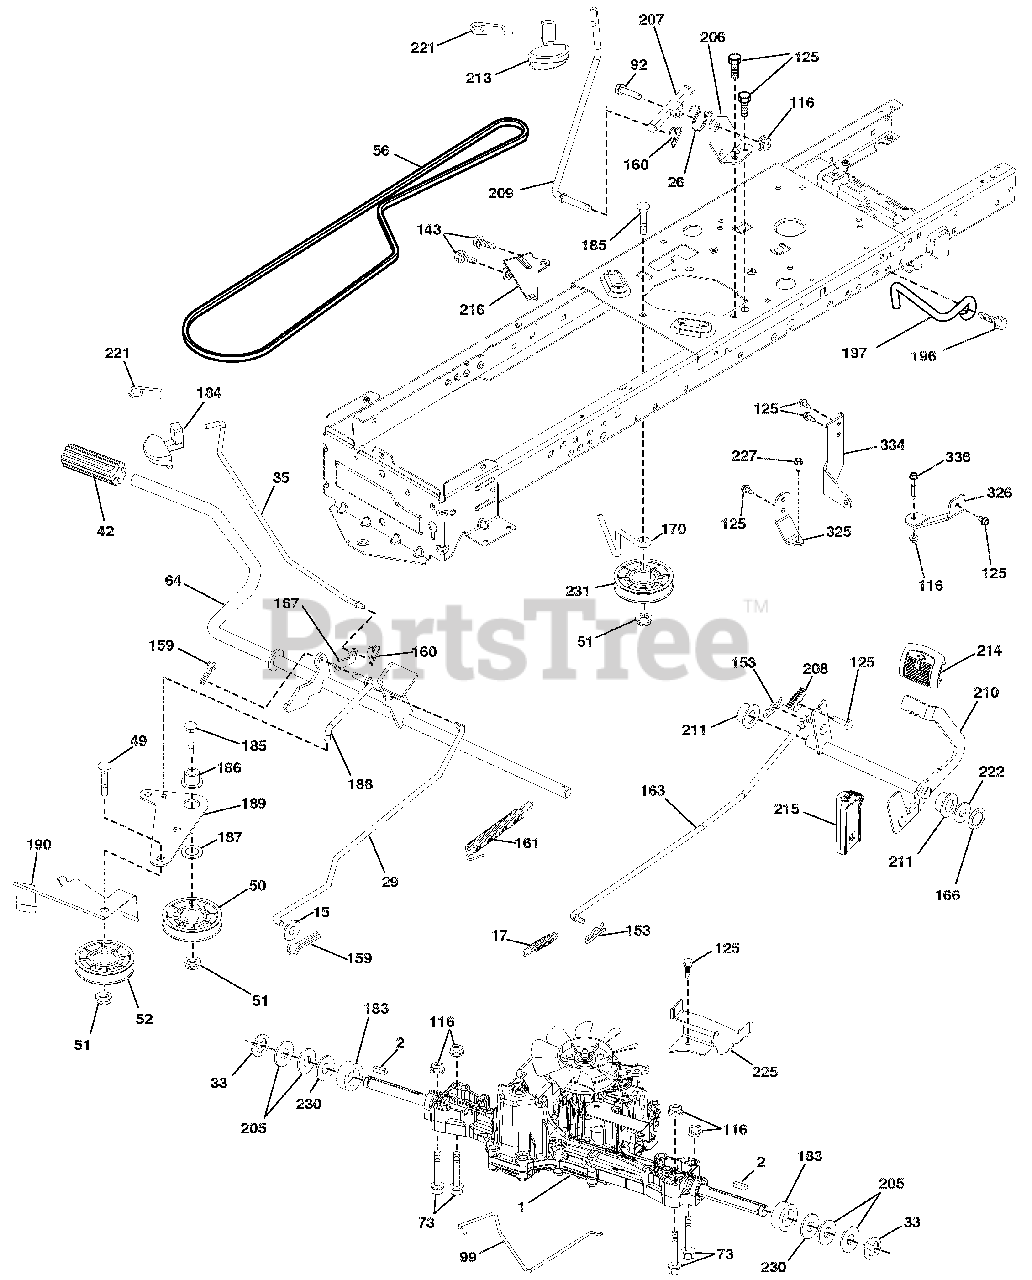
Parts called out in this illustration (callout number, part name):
1	TRANSAXLE, TUFFTORQ K46BT (426120)(ORDER PARTS FROM TRANSAXLE MANUFACTURER.)
2	KEY.SQUARE.2.0 X .1845/.1865
15	WASHER.13/32 X 13/16 X 16 GA.
17	SPRING.BRAKE.K46.GREEN
26	SPRING.RETURN.CRUISE
29	ROD.BRAKE.K46
33	E-RING.#5133-75
35	ROD.BRAKE.PARKING.LT.TEX
42	COVER PEDAL BLK ROUND
49	BOLT.RDHD.3/8-16UNCX1-3/4.GR5
50	IDLER.FLAT.910"OFFSET
51	Nut, Hex, Flangelock 3/8-16
52	IDLER.V-GROOVE.910"OFFSET
56	V-BELT.MOWER.92.40.42/K46
64	SHAFT ASM.PEDAL.BRK.CNTRL.PCH
73	BOLT 5/16-18 X 2 1/2 G.5
92	Bolt, Hex Head 5/16-18 x 1-1/4
99	ROD.SPRING.BYPASS.K46.LT.Z
116	Nut, Lock Hex Flange 5/16-18 u
125	SCREW.5/16-18X3/4.SMGML.TAP/BL
143	SCREW.THDROL.5/16-18 X 1/2TYTT
153	RETAINER SPRING
159	PIN.COTTER.1/8 X 3/4.CAD.
160	RETAINER.CLIP(M).DIA.290
161	SPRING.RETURN.CLUTCH.6.75
163	ROD CONTROL
166	NUT PUSH .625
167	LATCH.BRAKE.PARKING
170	KEEPER.CENTER SPAN.1.688
183	SPACER.AXLE.HYDRO/PEERLES
184	HANDLE.PARK.BRAKE
185	BOLT.RDHD.3/8-16UNC X2-3/4 GR5
186	SPACER.RETAINER
187	WASHER.13/32 X 2 X 10 GA.
188	LINK.CLUTCH.GROUND DRIVE
189	BELLCRANK.GROUNDRIVE.NSTG/NSTL
190	KEEPER.BELLCRANK.DRIVE.GROUND
196	SCREW.3/8-16X1.SMGML.TAP/R.BLK
197	LINK CLUTCH ANTI-ROTATION
205	WASHER.25/32 X 1-5/8 X 16GA.
206	BRACKET MOUNT LATCH CRUISE
207	LATCH.CONTROL.CRUISE
208	GEAR SECTOR.CONTROL.CRUISE
209	ROD.CONTROL.CRUISE
210	ROCKER ASM.PEDAL CONTROL.TEXLT
211	BEARING.NYLON.BLK..629 ID.
213	KNOB.CONTROL.CRUISE
214	PAD PEDAL FORWARD
215	PEDAL REVERSE
216	BRACKET.PULLEY.IDLER.WTEX
221	RETAINER.SPRING.CLIP.HANDLE
222	WASHER.21/32X1-1/4.10GA.N/PLTD
225	KEEPER.BELT.TRANSAXLE.K46
227	SCREW 5/16-18 X 3/4
230	WASHER.HARDEN..793 X 1.637X060
231	IDLER.V-GROOVE.1.688"OFFSET
325	STRAP.TORQUE.K46 LH
326	STRAP.TORQUE.K46 RH
334	BRACKET
